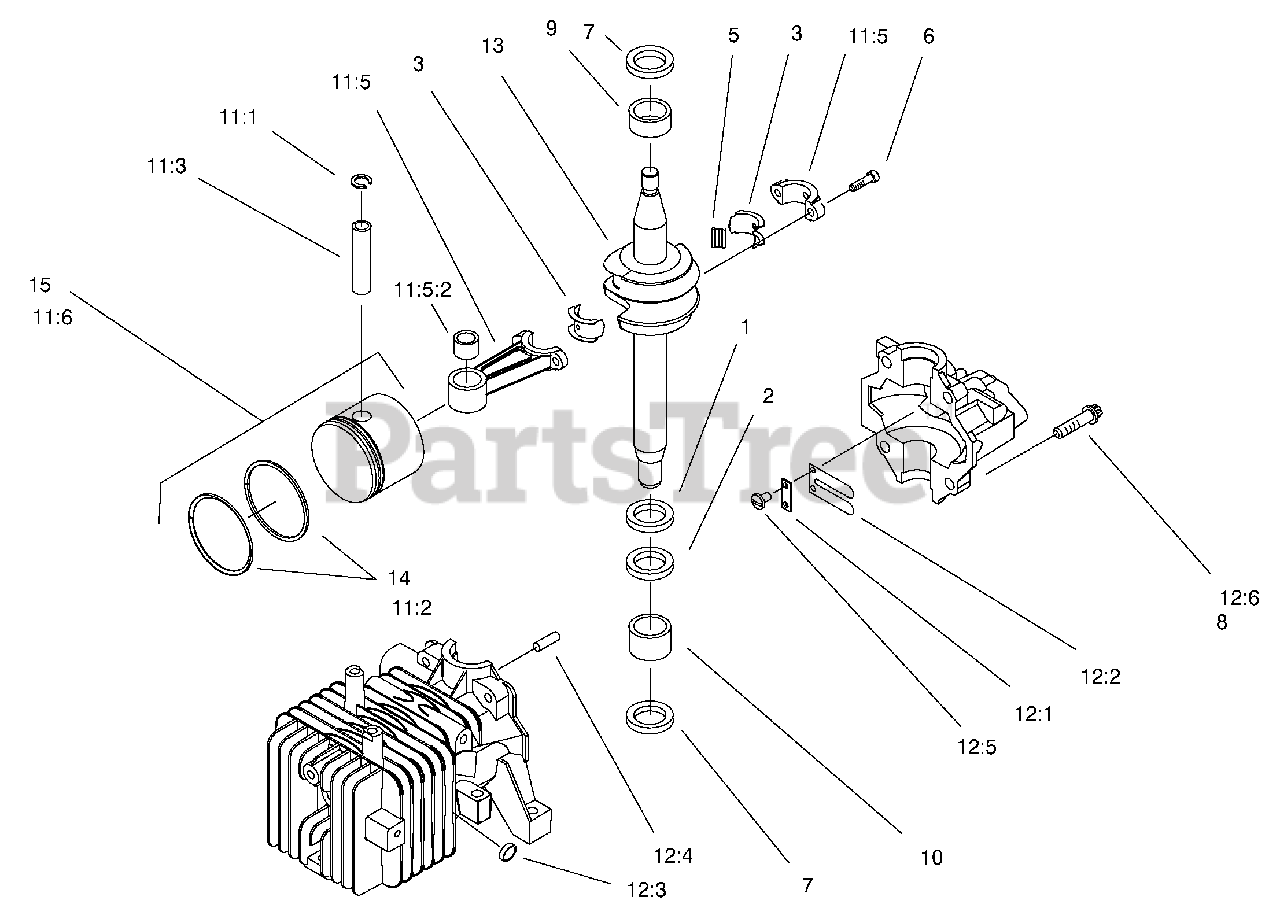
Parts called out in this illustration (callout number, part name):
1	Bearing-Thrust
2	Washer-Thrust
3	Liner ASM
5	Bearing-Needle
6	Screw-HSH
7	Seal-Oil
8	Screw-HWH
9	Bearing V
10	Bearing
11	Piston & Connecting Rod
11:1	Ring-Retaining
11:2	F-Ring Set
11:3	Pin-Wrist
11:5	Connecting Rod ASM
11:5:2	Bearing Xev
11:6	Piston & Ring
12	Cylinder & Crankcase ASM
12:1	Cyl & C/Case V
12:2	Screw-HWH
12:3	Plug-Core
12:4	Dowel Xev
12:5	Screw-HH
12:6	Plate-Backup, Reed
12:7	Reed-Carburetor
13	Crankshaft
14	F-Ring Set
15	Piston & Ring
